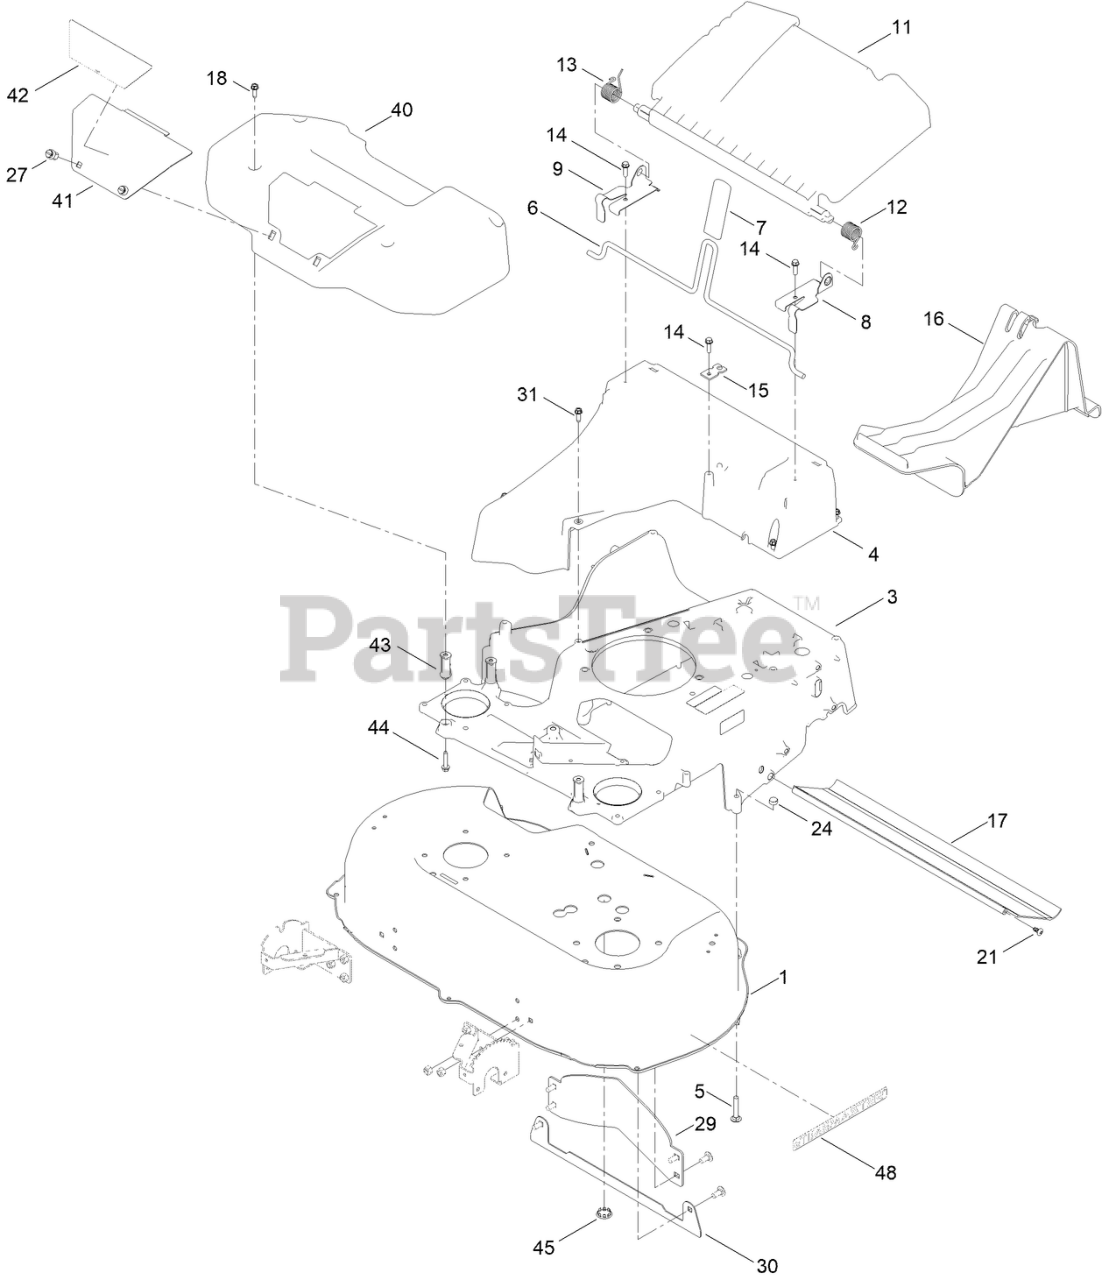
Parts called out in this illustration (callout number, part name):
1	HOUSING ASM
3	FRAME-30IN, 60V
5	BOLT-CAR
6	ROD-RELEASE, HANDLE
7	GRIP-LEVER
8	BRACKET-DOOR, LH
9	BRACKET-DOOR, RH
11	REAR DEFLECTOR ASM
12	SPRING-TORSION
13	SPRING-TORSION
14	SCREW-PLASTITE, HWH
15	BRACKET-CABLE, TRACTION
16	PLUG-MULCH
17	SHIELD-TRAILING
18	SCREW-HWHTF
21	SCREW-THD
24	NUT-HEX
27	FASTENER
29	BAFFLE-CONTROL
30	PLATE-DECK
31	SCREW-HWHTF
40	COVER-BELT
41	PANEL-ACCESS
42	DECAL-ACCESS PANEL
43	SPACER-FRAME, 30 IN.
44	SCREW-HWHTF
45	PLUG-BUTTON
